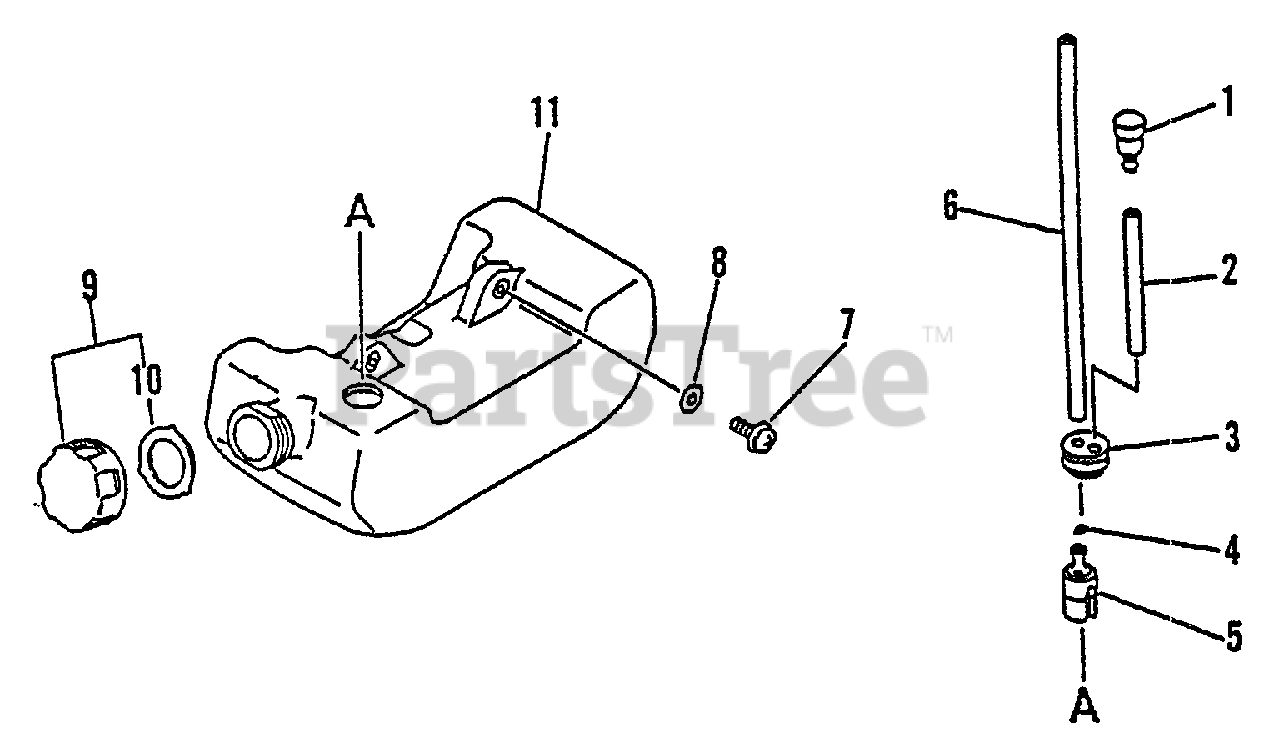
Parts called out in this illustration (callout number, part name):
1	VENT ASSY
2	PIPE, FUEL 3x-5x-70 BLACK
3	GROMMET, FUEL
4	CLIP 6 MM
5	FILTER, FUEL
6	PIPE, FUEL 3x-5x-180
7	SCREW 5×16
8	WASHER 5.5×12×0.8
9	CAP ASSY
10	GASKET, FUEL CAP
11	TANK, FUEL
